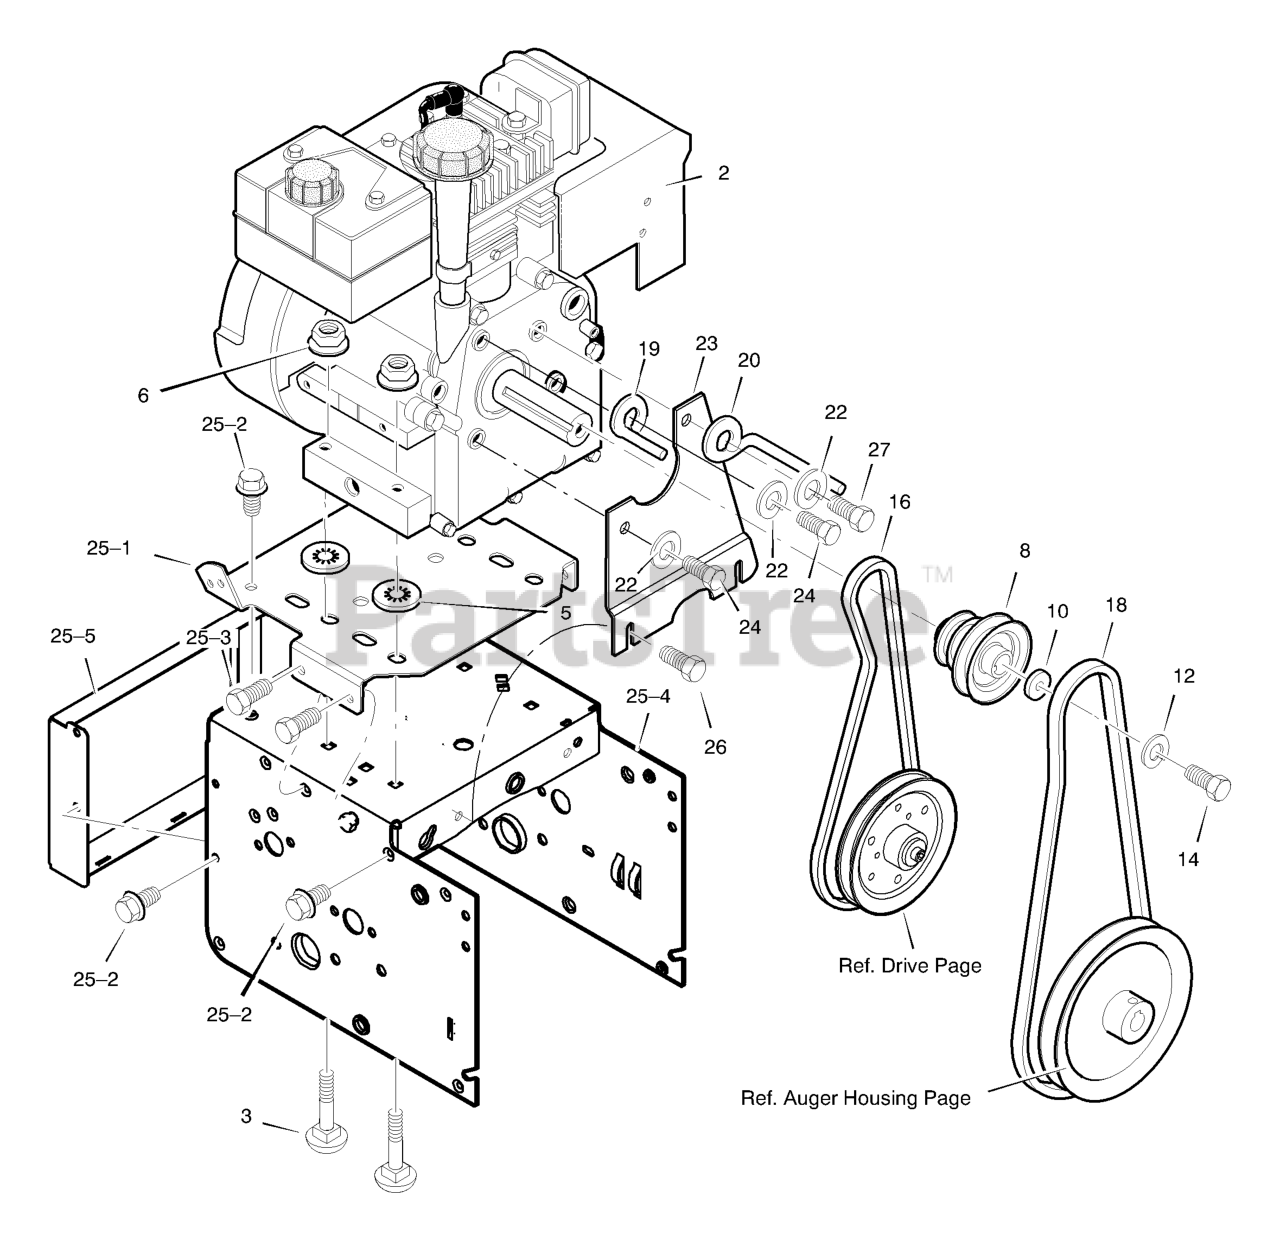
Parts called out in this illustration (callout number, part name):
2	ENGINE
3	BOLT, CARRIAGE 5/16-18
5	RETAINER, PUSH
6	NUT, HEX 5/16-18
8	PULLEY, ENGINE
10	WASHER
12	WASHER
14	SCREW, 3/8-24 x 1.00
16	BELT, HYDRO DRIVE
18	BELT, AUGER V 4L
19	GUIDE, BELT
20	GUIDE, BELT
22	WASHER, .31X.58X.08
23	PLATE, VIBRATION
24	SCREW, 5/16-24 x 0.75
25	FRAME ASSEMBLY
25-1	PLATE, ENGINE MOUNT
25-2	SCREW, TAP 1/4-20 X .63
25-3	SCREW, TAP 5/16-18 X .50
25-4	FRAME, MOTOR BOX
25-5	PANEL, BACK - HYDRO
27	BOLT, HEX 5/16-24 X 1.00
